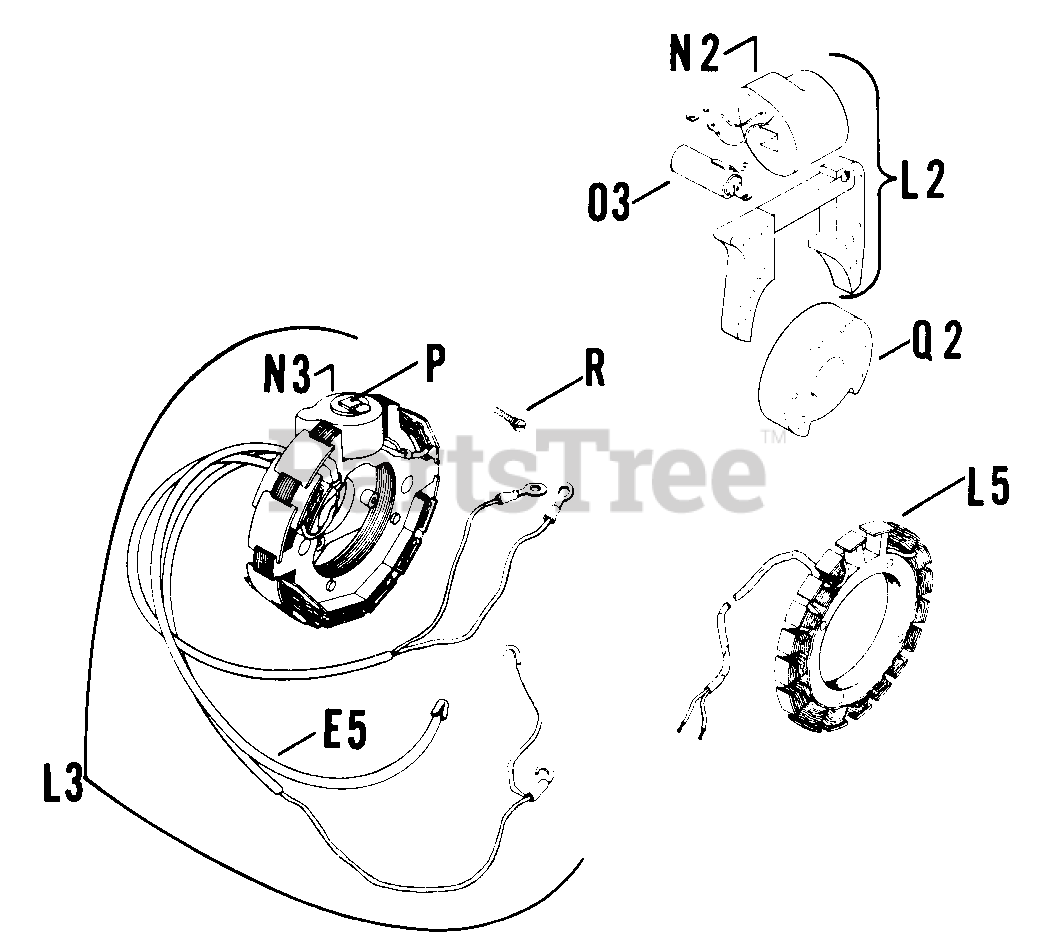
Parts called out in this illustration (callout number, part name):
L2	STATOR - DISCONTINUED
N2	COIL - DISCONTINUED
O3	CONDENSER
Q2	ROTOR - DISCONTINUED
